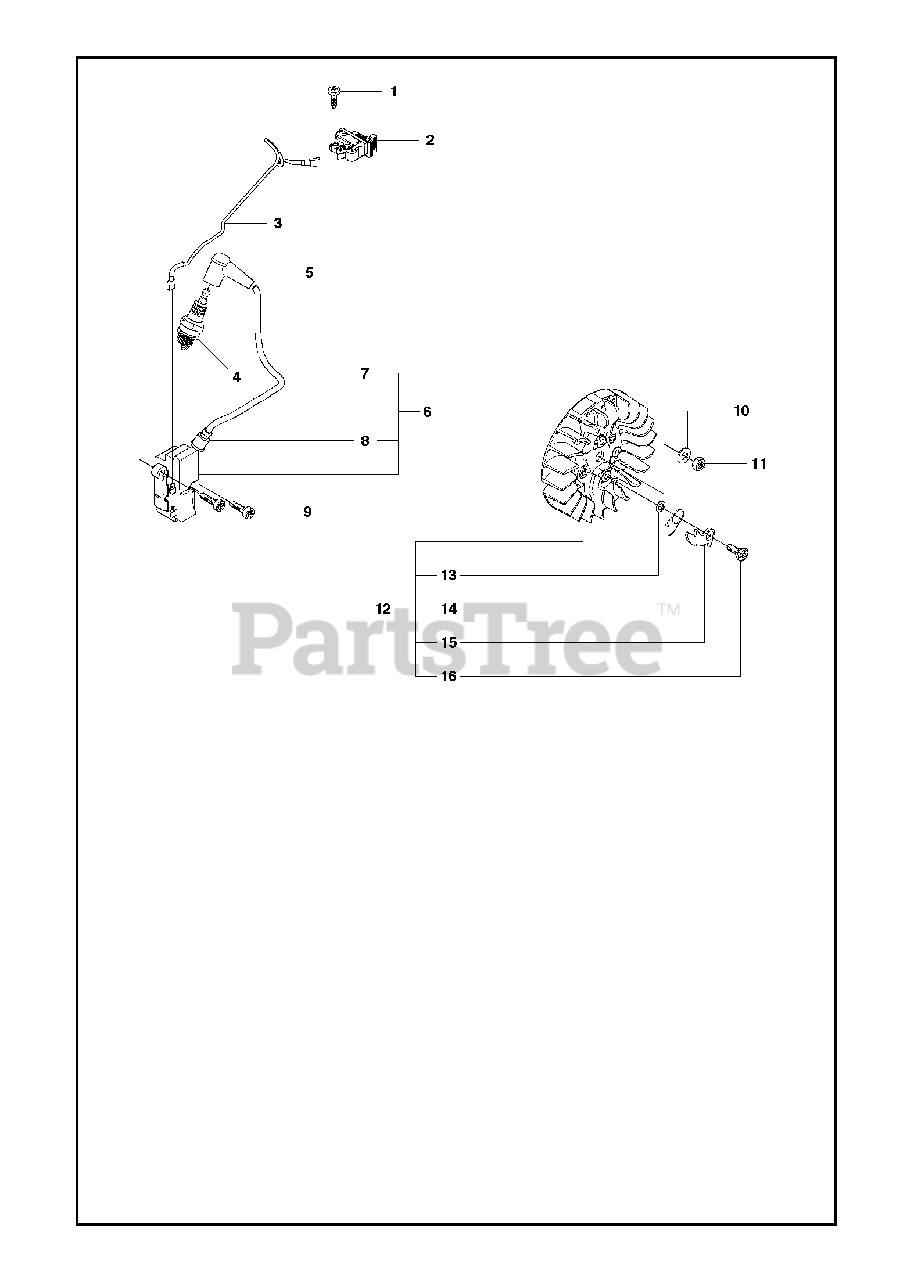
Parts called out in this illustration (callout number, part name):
1	SCREW CCRPANT
2	STOP SWITCH
5	SPARK PLUG CAP
6	IGNITION MODULE
7	IGNITION CABLE
9	SCREW ITXSCM
12	FLYWHEEL
16	SCREW
